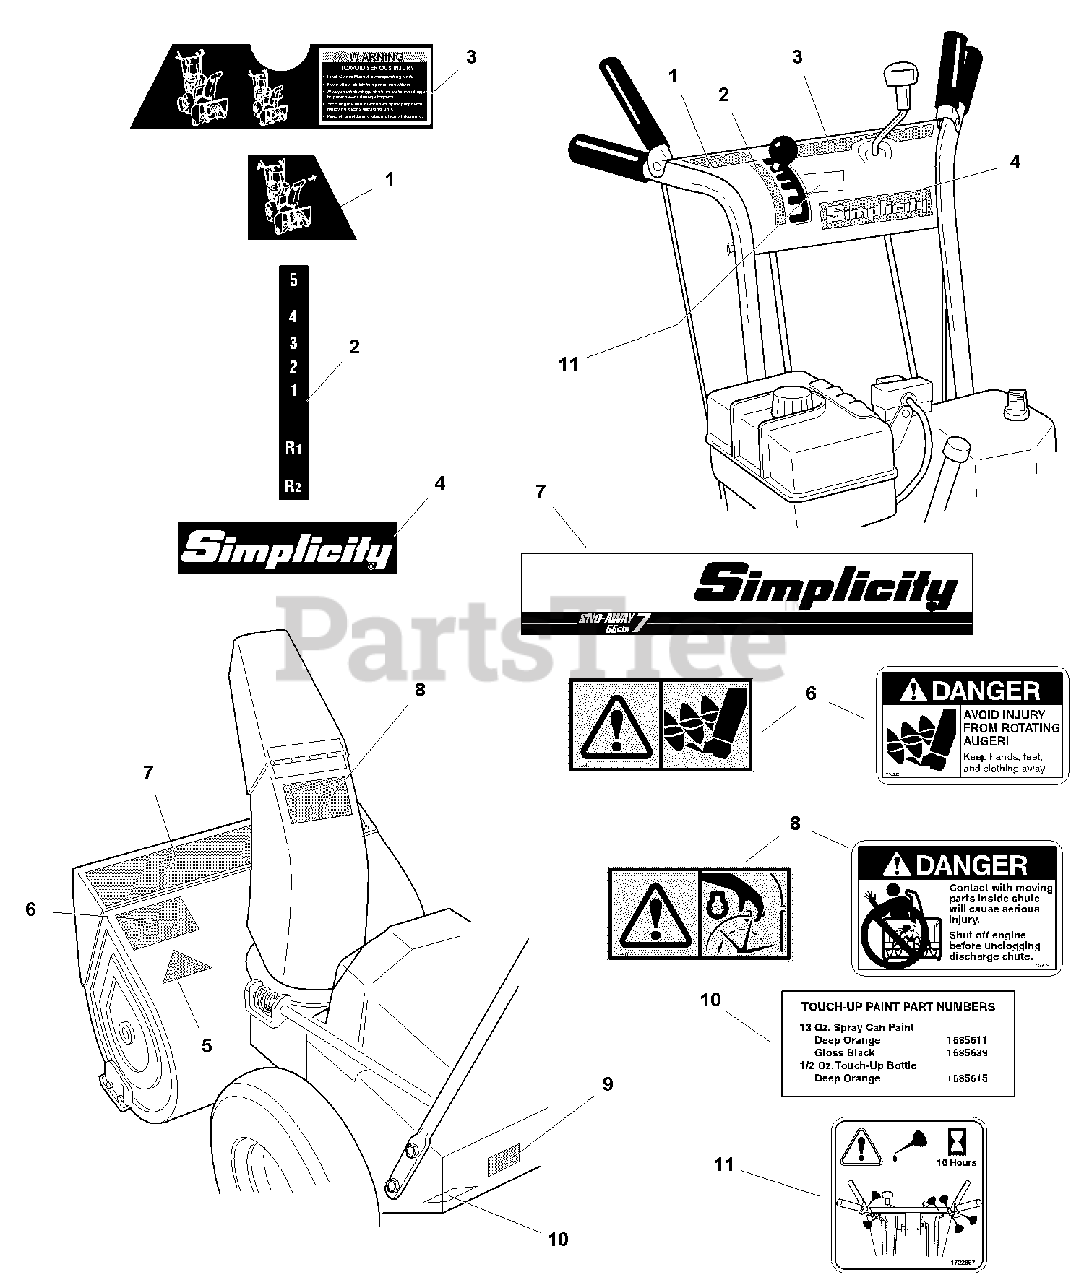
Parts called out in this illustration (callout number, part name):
1	DECAL, Auger Control
1	DECAL, Auger Control (1693984 & 1693985)
2	DECAL, Speed Selector
3	DECAL, Warning / Main Dash Panel
3	DECAL, Warning / Main Dash Panel (1693985)
3	DECAL, Warning / Main Dash Panel (1693984)
4	DECAL, Simplicity Logo
5	DECAL, OPEI (Not Serviced)
6	DECAL, Auger Danger
6	DECAL, Auger Danger (Export)
7	DECAL, Stripe
8	DECAL, Discharge Chute Danger
8	DECAL, Discharge Chute Danger (Export)
9	I.D. Tag (Not Serviced)
10	DECAL, Touch-up Paint
11	DECAL, Handle Lubrication (1693984 & 1693985)
